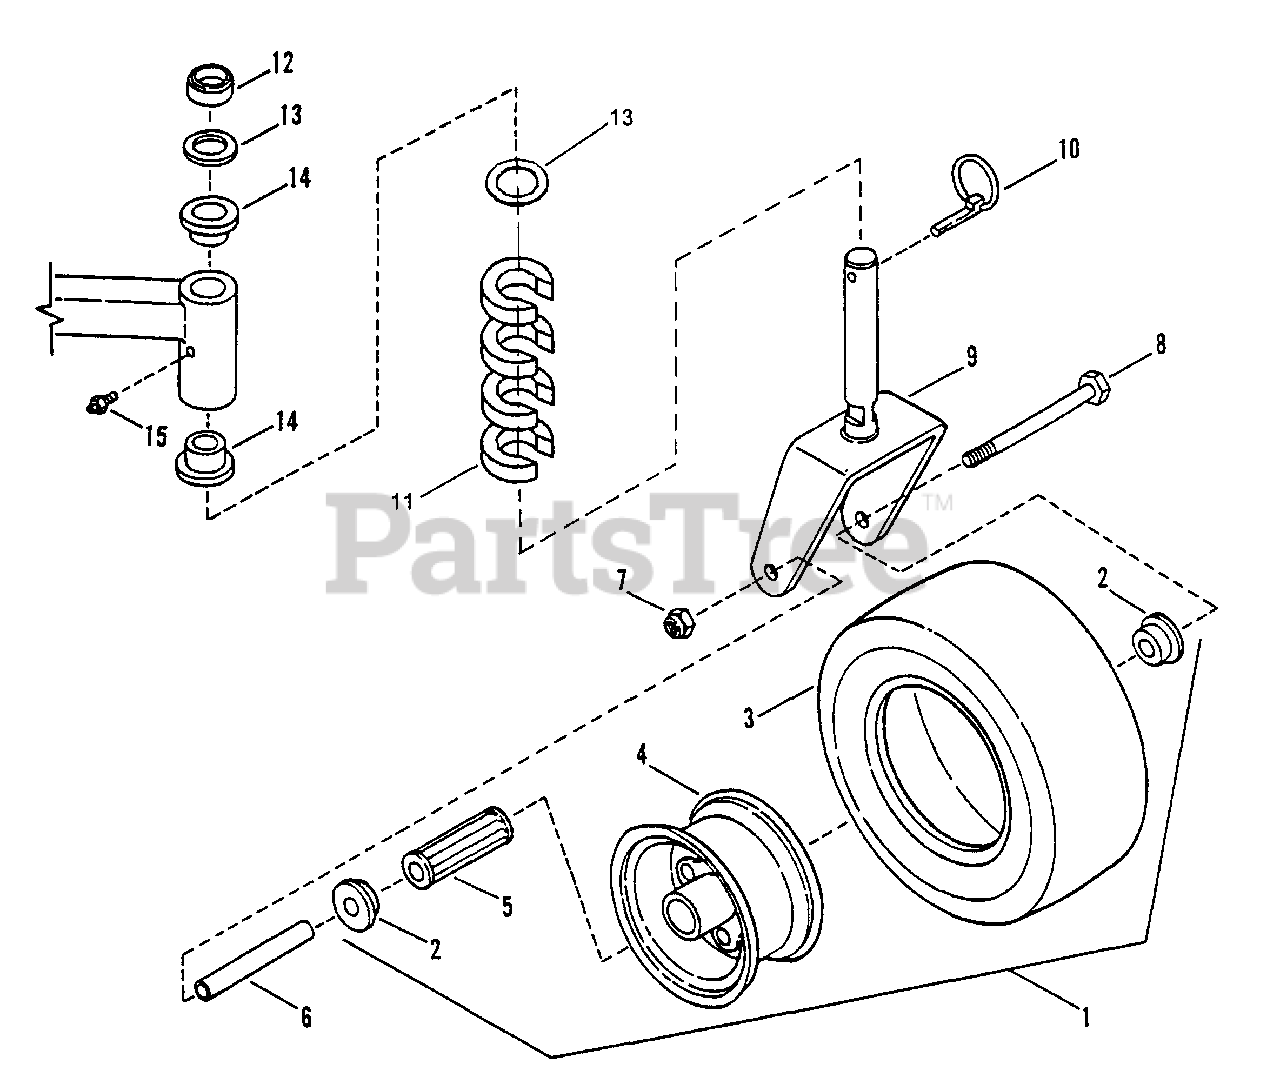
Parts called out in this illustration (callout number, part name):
1	ASSEMBLY, Wheel & Tire
2	RETAINER, Flanged
3	TIRE, 9 x 3.50-4
4	ASSEMBLY, Wheel
5	BEARING, Roller
6	SLEEVE, Axle
7	NUT, 1/2-13 HEX NYLON LOCK
8	BOLT, 1/2-13 X 5-1/2" GD5 YZ
9	YOKE, Caster Weldment
10	PIN, Lynch 7/16" Heavy Duty
11	SPACER
12	SPACER, 1" x 1 3/8 x .30" (PM)
13	BUSHING, 1"
14	BUSHING, Caster
15	FITTING, Lube
